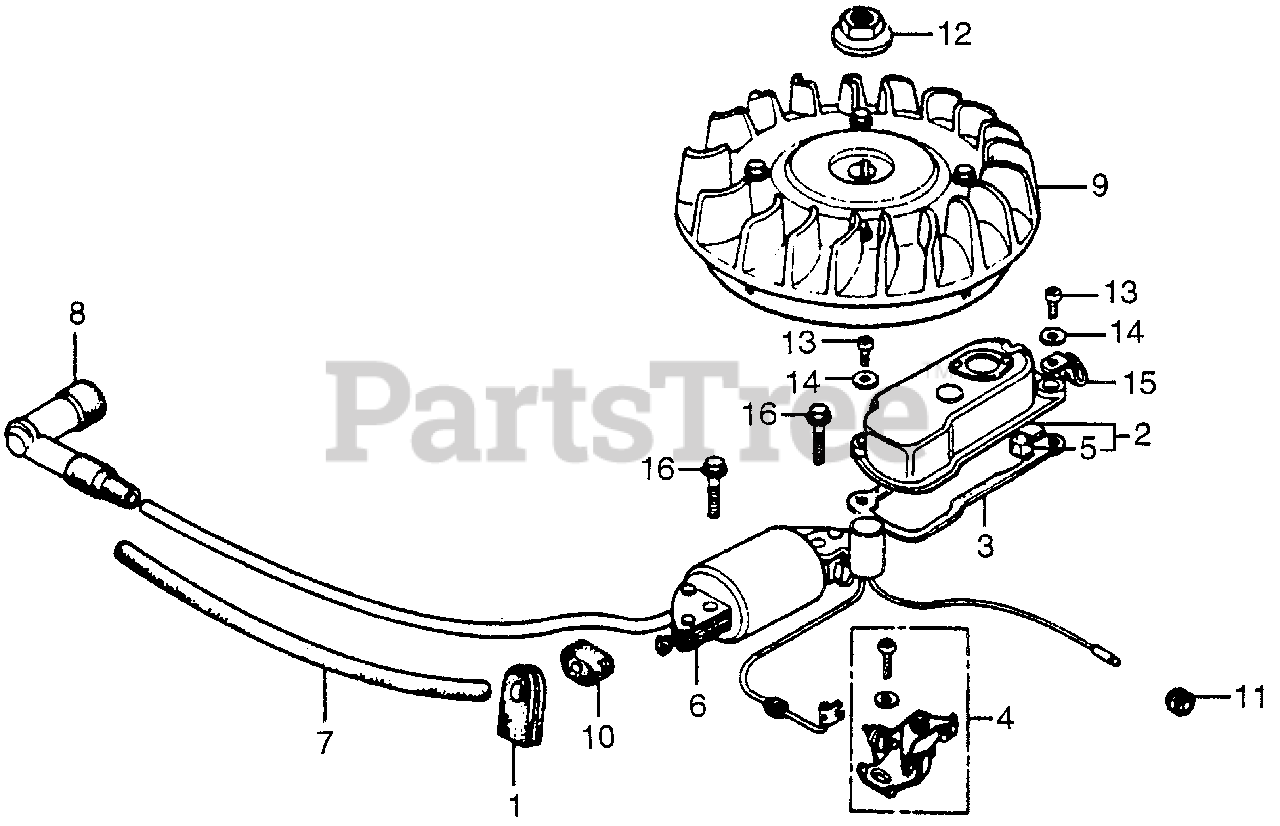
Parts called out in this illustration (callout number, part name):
1	GROMMET, WIRE
2	COVER ASSY., POINTS (NOT AVAILABLE)
3	GASKET, POINT COVER (NOT AVAILABLE)
4	POINTS ASSY.
5	FELT, OIL
6	COIL ASSY., IGNITION (DENSO) (NOT AVAILABLE)
7	TUBE, IGNITION RUBBER
8	CAP ASSY., NOISE SUPPRESSOR
9	FLYWHEEL ASSY.
10	GROMMET, WIRE
11	GROMMET, RR. TURN SIGNAL CABLE (NOT AVAILABLE)
12	NUT, SPECIAL (14MM)
13	SCREW, PAN (4X8)
14	WASHER, PLAIN (4MM)
15	CLIP (2X40)
16	BOLT, FLANGE (6X25) (NOT AVAILABLE)
